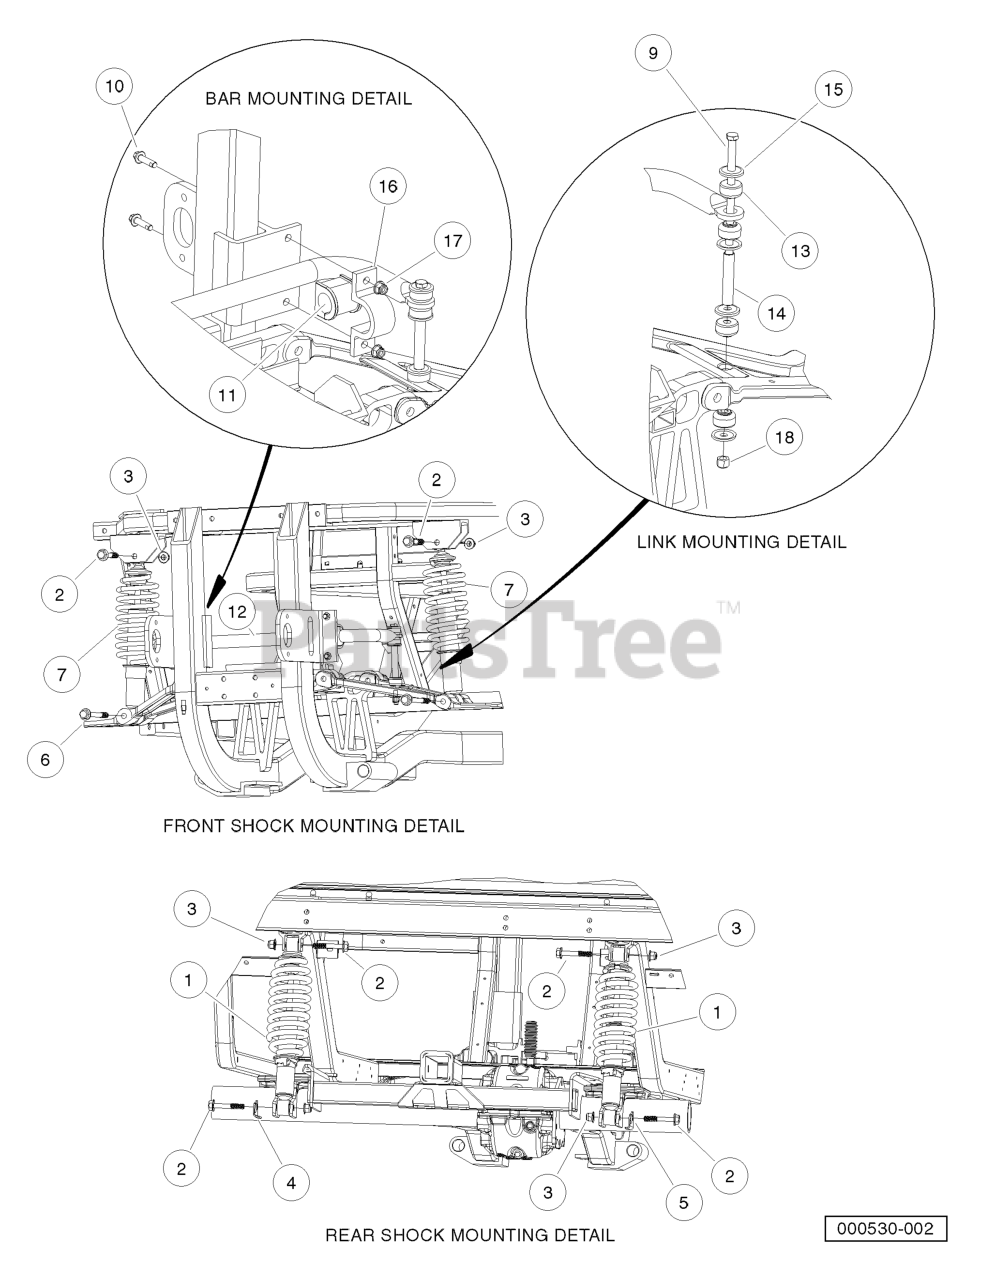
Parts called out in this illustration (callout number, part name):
1	SHOCK, COIL OVER, REAR HD
2	BOLT, FLG, M12X1.75X70
3	NUT FLG, M12X1.75, NYLON GR 10
4	BRKT, LINE, HYD, SHK MNT, DRV
5	BRKT, LINE, HYD, SHK MNT, PASS
6	BOLT FLG, M12X1.75X100, PATCH
7	ASM, COIL & SHOCK, FRT
8	Instl, Bar, Antisway, Wide Frt
9	SCREW, 3/8-16 X 7.00 HEX CAP
10	BOLT - FLANGED HD, M8 X 30.0
11	BUSHING, ANTI-SWAY BAR, 1-1/8
12	BAR, SWAY, FORMED
13	BUSHING, LINK
14	SLEEVE, LINK
15	WASHER, CUP, BUSHING
16	BRACKET, ANTI-SWAY BAR
17	LOCK NUT, FLG M8 X 1.25 NYLON
18	LOCKNUT, 3/8-16 HEX
